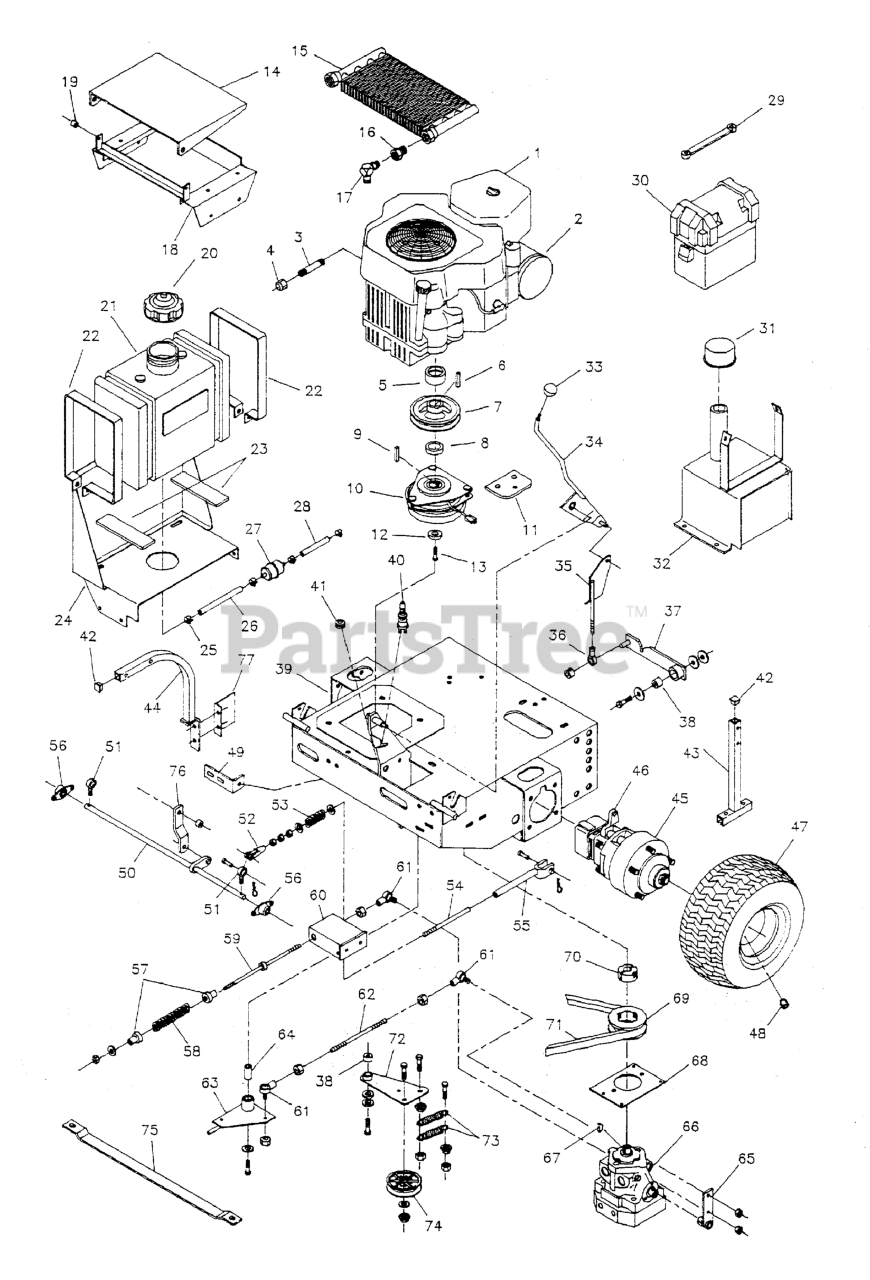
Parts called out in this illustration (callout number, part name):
2	MUFFLER, Kohler
3	NIPPLE, 3/8 NPT X 4-1/2
4	CAP, 3/8 NPT
5	SPACER, 1.13 X 1.75 X .50
6	KEY, 1/4 SQ. X 1-1/4
7	PULLEY, Pump Drive
8	SPACER, 1.13 x 2.00 x .19
9	KEY, 1/4 SQ. X 1
10	CLUTCH, Electric, 1-1/8" Shaft
11	CLUTCH ANCHOR PAD
12	SPACER, .45 x 1.62 x .37
13	CRANKSHAFT BOLT, 7/16 x 3
14	OIL COOLER HOOD
15	OIL COOLER
16	FITTING, Reducer
17	FITTING, NPT - Hose, 90 Deg.
18	OIL COOLER MOUNT
19	SPACER, .27 x .75 x .94
20	CAP, GASOLINE, VENTED
21	TANK, FUEL, PLASTIC, 6 GALLON W/ FUEL LINE
22	FUEL TANK STRAP
23	RUBBER PAD
24	FUEL TANK MOUNT
25	CLAMP, Hose
26	1/4" Fuel Line, 35" Long
27	FUEL FILTER
28	FUEL LINE
29	RUBBER STRAP
30	BOX, Battery
31	BREATHER
32	HYDRO TANK WELDMENT
33	KNOB
34	PARKING BRAKE LEVER
35	BRAKE LOCK LINK
36	BALL JOINT 5/16-24 RH FEMALE BRONZE RACE
37	NEUTRAL LOCK LEVER, Complete
38	SPACER, .32 x .75 x 1.06
39	ENGINE DECK
40	SWITCH, Plunger, NO
41	GROMMET, 1/2"
43	OIL COOLER MOUNT - RH
44	OIL COOLER MOUNT - LH
45	HYDRAULIC WHEEL MOTOR
46	BRAKE LEVER
47	WHEEL & TIRE ASSEMBLY, 23 x 10.5-12, White, Complete
48	LUG NUT, 1/2-20
49	CABLE BRACKET
50	SHAFT, Brake
51	BALL JOINT, 3/8-24 Male
52	CLEVIS, 3/8-24, Plastic
53	SPRING, Compression
54	BRAKE SPRING ROD
55	BRAKE TUBE
56	5/8" Triangle Bearing
57	GUIDE, Spring Return
58	SPRING, Compression
59	SPRING RETURN ROD
60	BOX, Spring Mount
61	BALL JOINT 5/16-24 LH FEMALE W/STUD, BR
62	CONTROL ROD
63	SPEED CONTROL PIVOT, Complete
64	SPACER, .33 X .75 X 1.56
65	LEVER, Pump Control
66	HYDRAULIC PUMP
67	KEY, #61 Woodruff
68	PLATE, Pump Mount
69	PULLEY, Tapered Hub
70	BUSHING, Tapered Hub
71	BELT
72	ARM, Idler
73	SPRING, Extension
74	PULLEY, Idler
75	BAR, Tie
76	BRAKE LINK
77	DEFLECTOR, Exhaust
